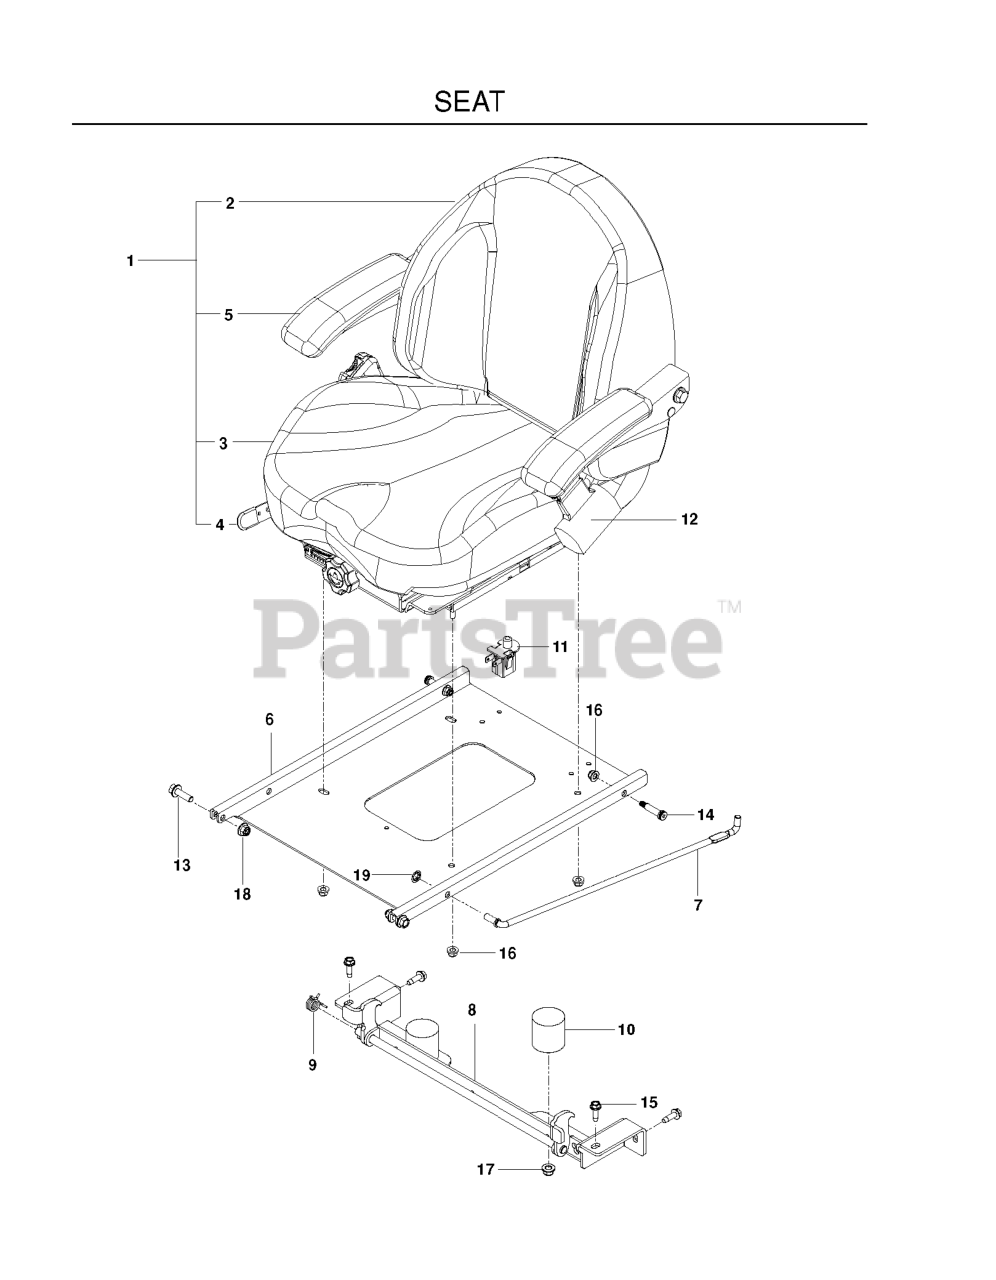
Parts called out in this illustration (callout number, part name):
1	Seat Assy
2	COVER, BACK
3	COVER KIT, CUSHION
5	ARMREST, RT
6	PAN, SEAT, BLACK
8	LATCH.SEAT.BLACK
9	SPRING, TORSION
10	BUMPER, RUBBER
11	SEAT SWITCH
12	SEAT BELT, RETRACTABLE
13	HHFS 3/8-16 X 1.25 GD 5
14	BOLT, SHOULDER 3/8 X 1.25
15	RP BLT 5/16-18 X 1 THRD FORM D
16	5/16-18 NYLOC FLANGE NUT
17	NUT 3/8-16 HEX FLG NYLOC ZD
18	NUT 3/8-16 HEX FLG NYLOC ZD
19	NUT 3/8 PALNUT RTNG BLK PHOS
